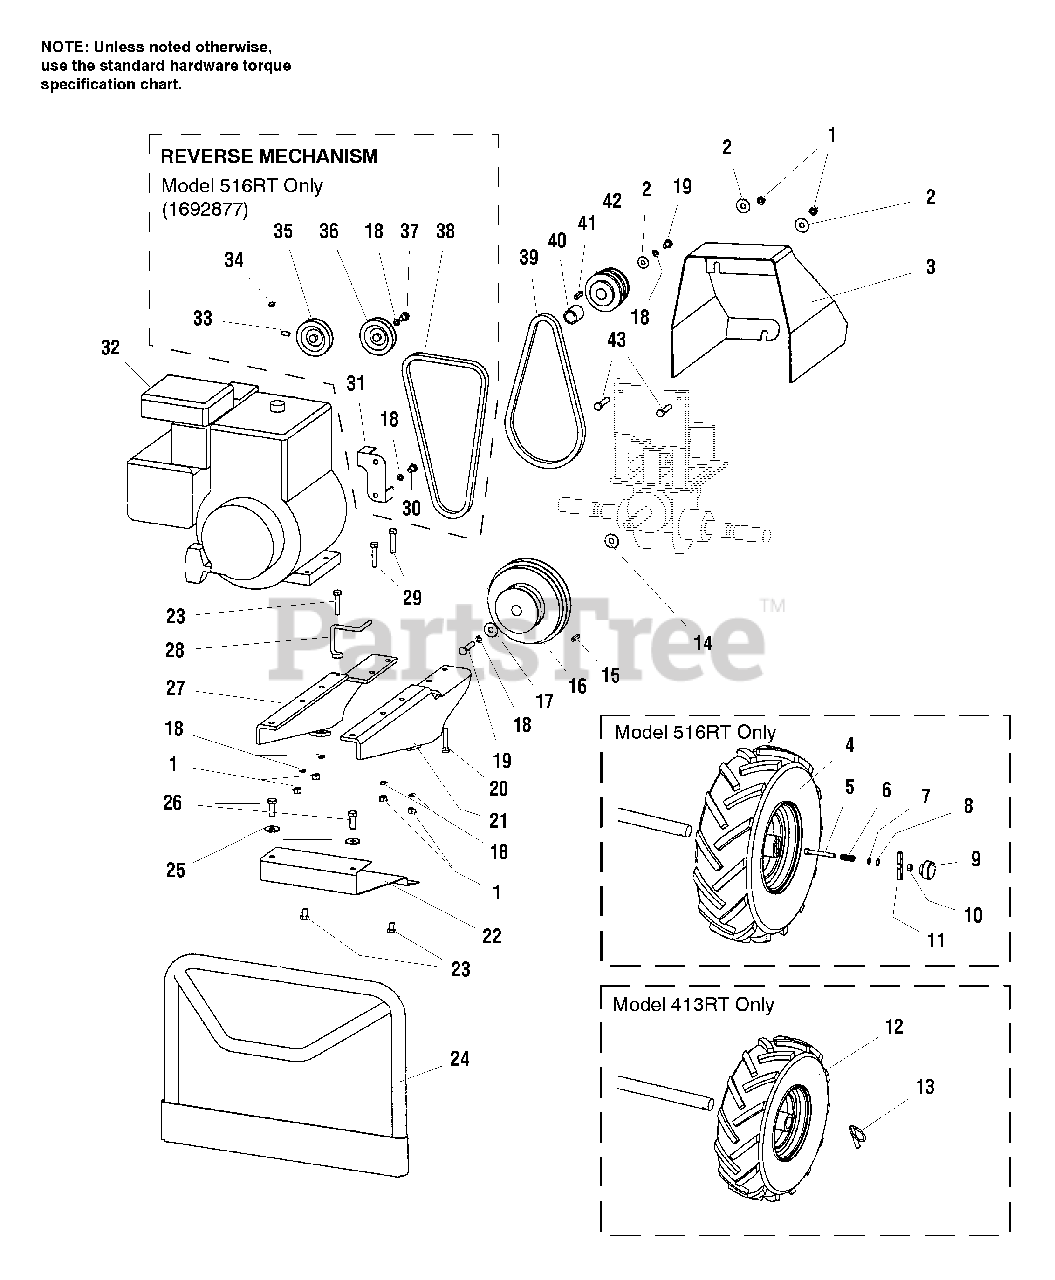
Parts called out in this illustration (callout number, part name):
1	NUT, 5/16"-18
2	WASHER, Flat, 5/16"
4	WHEEL, Tire Assembly, Left
4	WHEEL, Tire Assembly, Right
5	SCREW, Soc Hd, 1/4"-20 x 2"
6	SPRING
7	WASHER, 1/4" ID
8	SNAP RING
9	KNOB, Wheel Lockout
10	NUT, Keps, 1/4"-20
11	LOCKOUT, Set of 2
12	WHEEL, Tire Assembly, Left
12	WHEEL, Tire Assembly, Right
13	LOCKPIN
14	WASHER, Flat, 11/16" ID
15	KEY, 3/16" x 1"
16	PULLEY, Transmission
18	LOCKWASHER, Spring, 5/16"
19	BOLT, Hex Hd, 5/16"-24 x 3/4", Grade 5
20	SCREW, Soc Hd, 5/16"-18 x 1-1/4"
21	BRACKET, Engine Mount, Left Side
22	GUARD, Lower Pulley
23	BOLT, Hex Flange Hd, 5/16", 18 x 3/4"
24	BUMPER GUARD
25	LOCKWASHER, Spring, 3/8"
26	BOLT, Hex Hd, 3/8"-16 x 1", Grade 5
27	BRACKET, Engine Mount, Right Side
28	BELT GUIDE, Forward
29	SCREW, Hex Hd, 5/16"-18 x 1-3/4"
30	SCREW, Hex Hd, 5/16"-24 x 1/2"
31	BELT GUIDE, Reverse
33	SET SCREW, 1/4"-20 x 1/4"
34	KEY, Woodruff, #5
35	PULLEY, Engine Reverse
36	PULLEY, Belt Guide, V-Groove
37	BOLT, Hex Hd, 5/16"-24 x 1-1/2"
38	BELT, Reverse
39	BELT, Forward
40	SPACER, Engine Pulley
41	KEY, 3/16" x 1-1/2"
42	PULLEY, Engine Forward
43	CAPSCREW, Hex Head 5/16-18 x 2 G5
